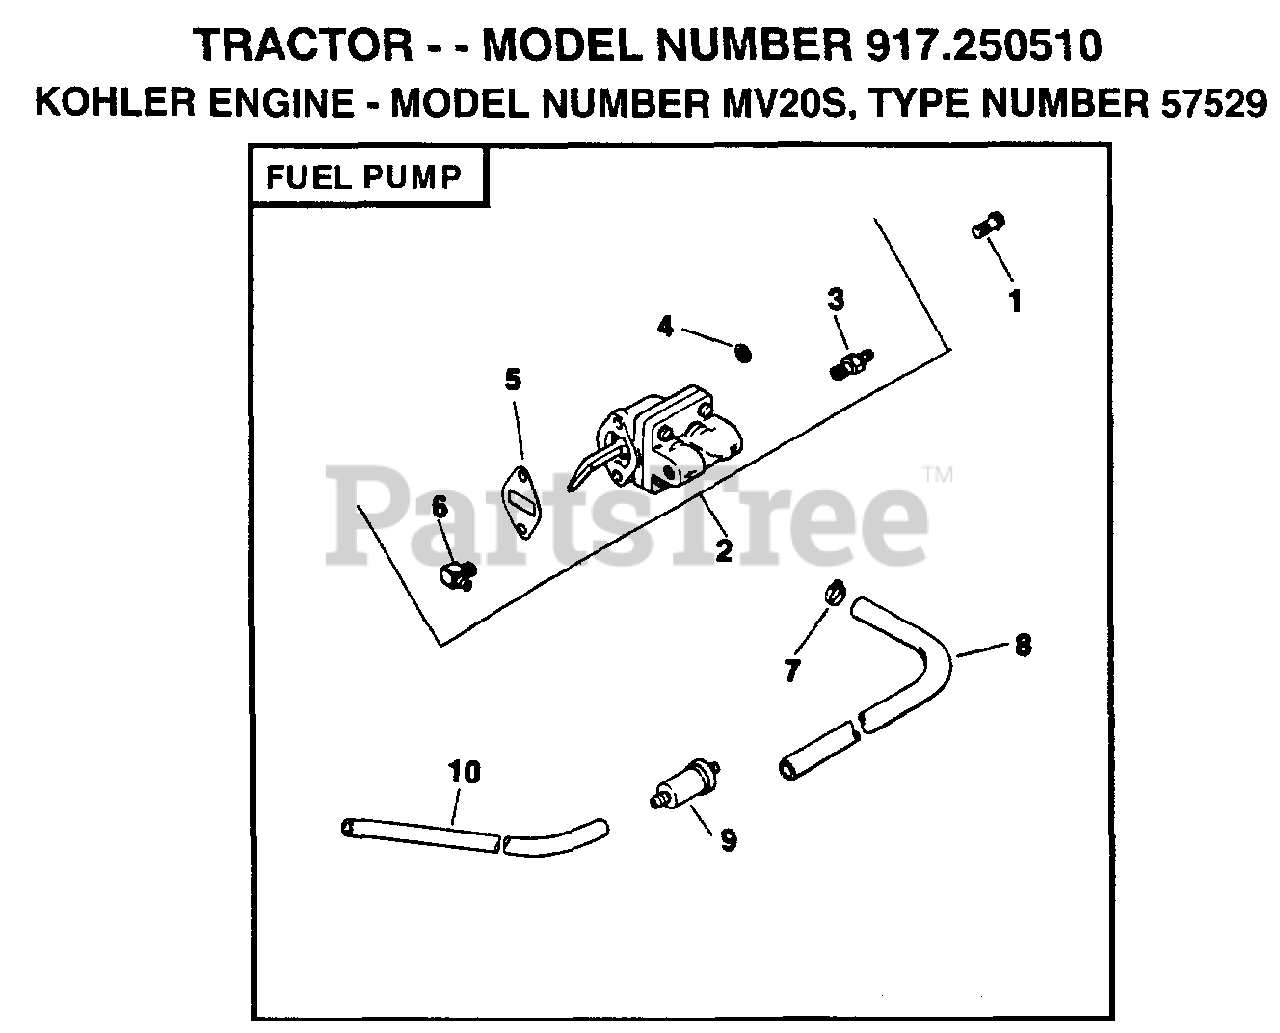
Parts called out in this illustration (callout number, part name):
3	CONNECTOR, HOSE
4	WASHER, PLAIN 1/4
7	CLAMP, HOSE
10	LINE, FUEL 8"
